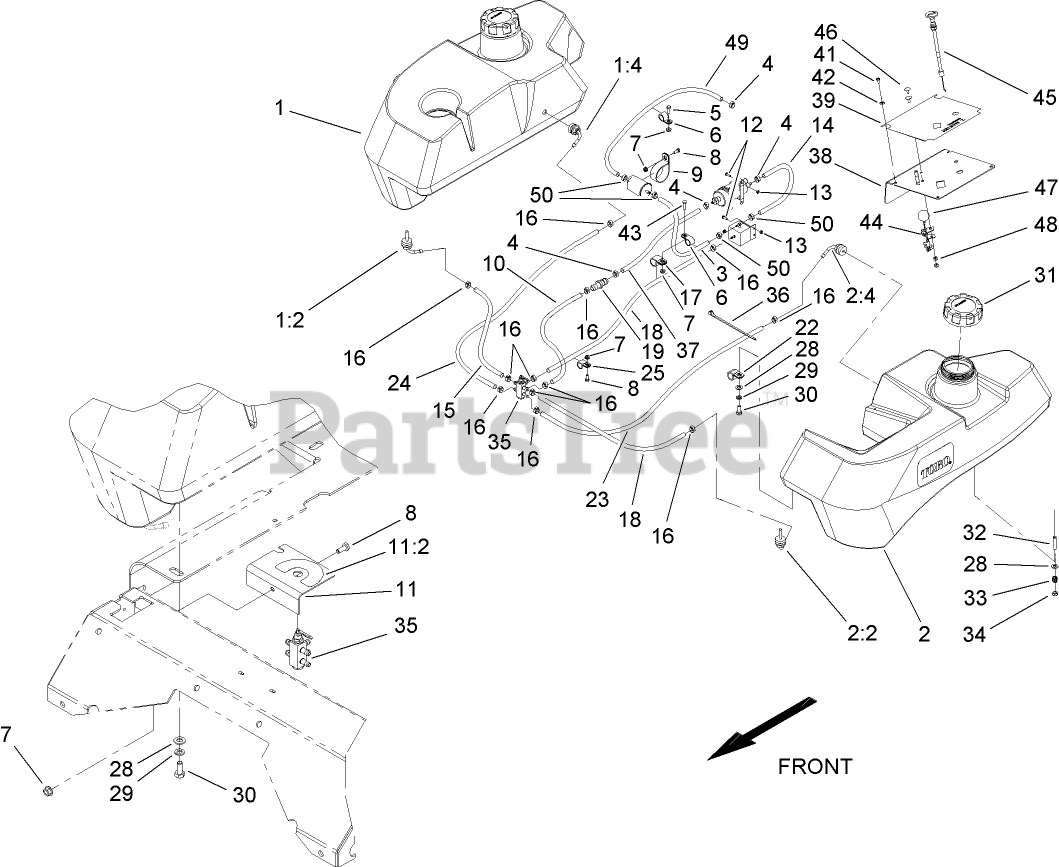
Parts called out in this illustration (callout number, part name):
1	RH FUEL TANK KIT ASM
1:2	FITTING-FUEL, BULKHEAD
1:4	Fitting-Fuel, Bulkhead
2	LH FUEL TANK KIT ASM
2:2	FITTING-FUEL, BULKHEAD
2:4	Fitting-Fuel, Bulkhead
3	HOSE, FUEL
4	CLAMP-HOSE, FUEL
5	SCREW-HH
6	CLIP-LOOM
7	NUT-HF
8	SCREW-HH
9	CLIP-LOOM
10	HOSE-FUEL
11	Fuel Valve Bracket Asm
11:2	DECAL-VALVE, FUEL
12	SCREW-PPH
13	NUT-LOCK, NI
14	Hose-Fuel
15	HOSE-FUEL
16	CLAMP-HOSE, FUEL
17	CLIP-LOOM
18	HOSE-FUEL
19	Connector
23	Hose-Fuel
24	Hose-Fuel
25	CLIP-LOOM
28	WASHER-PLAIN
29	WASHER-LOCK
30	SCREW-HH
31	CAP-FUEL, GAS
33	SPRING-TANK, FUEL
34	NUT-LOCK, NI
35	VALVE-FUEL, DUAL FLOW
36	TIE-CABLE
37	HOSE-FUEL
38	PANEL-CONTROL
39	Decal-Panel, Control
41	SCREW-PPH
42	WASHER-SPRING
43	SCREW-HH
44	CABLE-THROTTLE
45	Control-Choke, Push / Pull
46	BOLT-CARR
47	KNOB-BALL
48	NUT-LOCK, NI
49	Hose-Fuel
